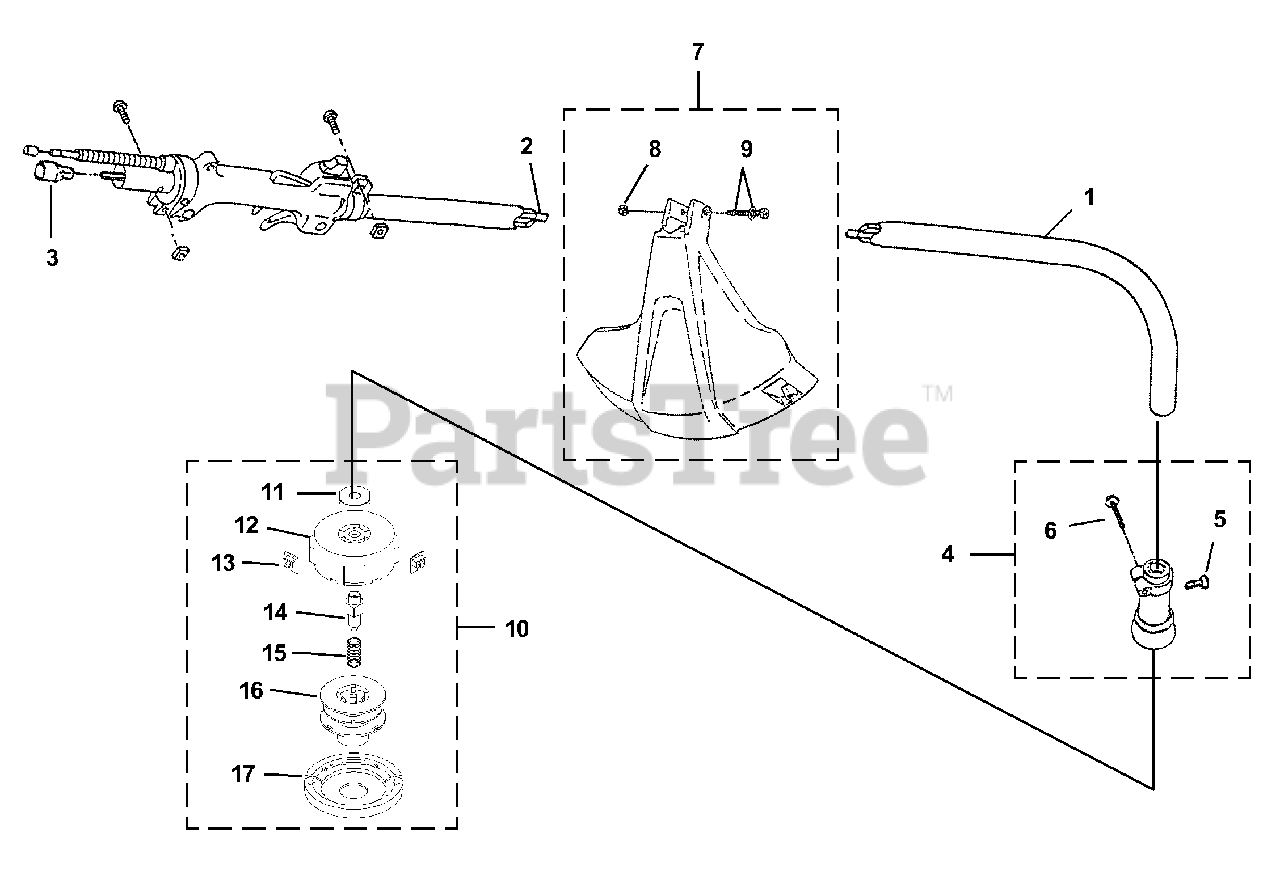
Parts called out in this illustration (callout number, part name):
1	DRIVESHAFT HOUSING
2	FLEX SHAFT
4	GEAR HEAD
7	DEFLECTOR ASSEMBLY
9	SCREW & WASHER
10	COMPLETE STRING HEAD
11	TOP PLATE
